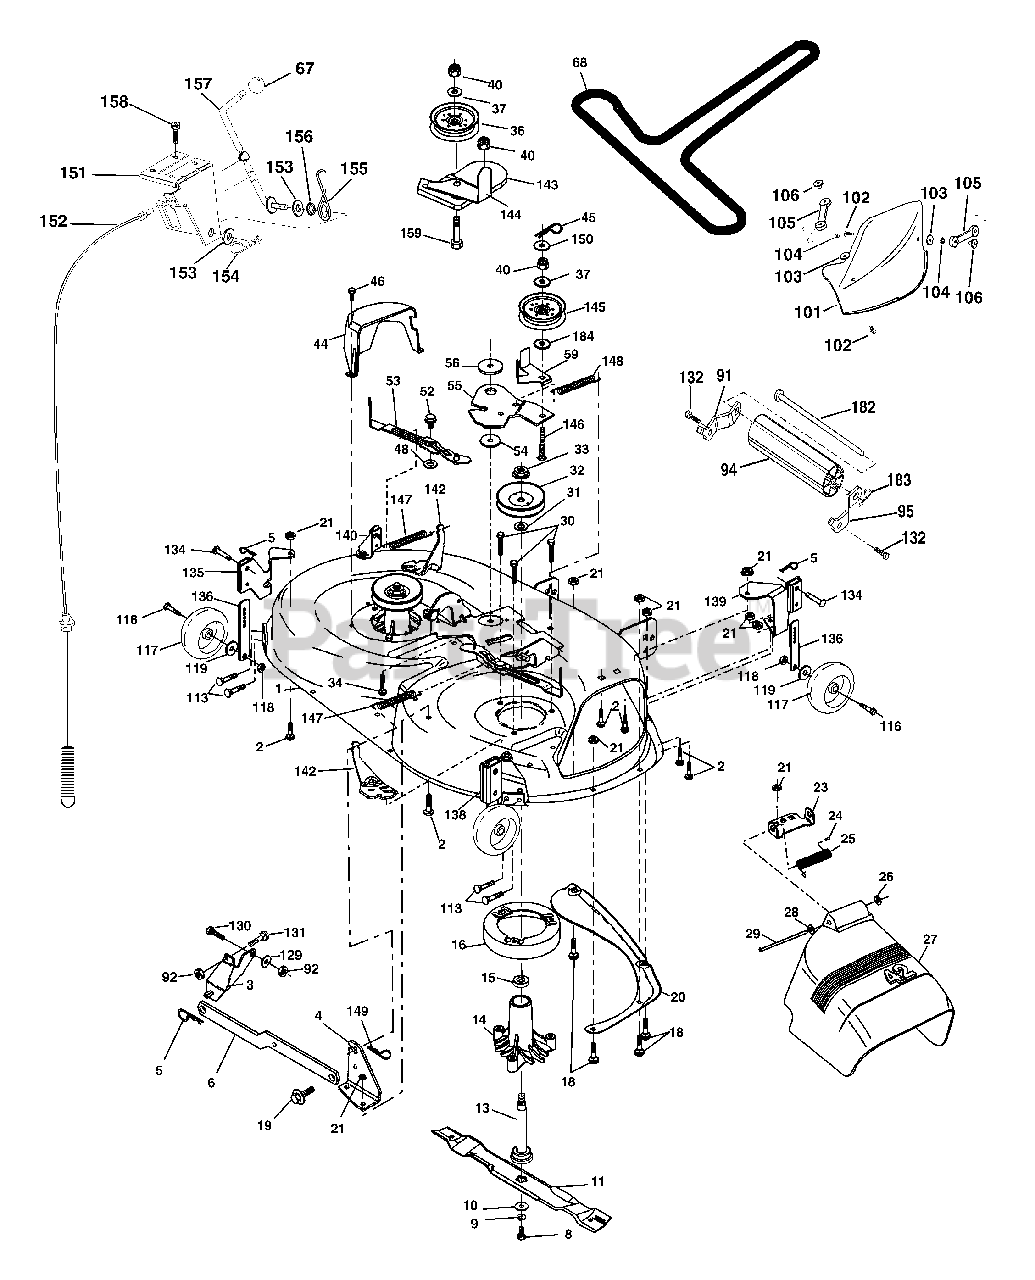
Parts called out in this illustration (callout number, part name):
1	Mower Deck Assembly, 42"
2	Bolt
3	Bracket Asm Fr. Sway Bar 3/42
4	Bracket Asm Deck 42" Sway Bar
5	Retainer Spring
6	Bar Sway Deck
8	Bolt 3/8-24 x 25 Grade 8 patched
9	Washer, Lock
10	Washer, Hardened
11	Blade, Mulching 42" Std
11	Blade Mulching 42" Premium
11	Blade Mower 42" Hi-Lift
13	Shaft Assembly, Mandrel, Vented
14	Housing, Mandrel, Vented
15	Bearing, Ball, Mandrel
16	Stripper, Mandrel Deck
18	Bolt, Carriage 5/16-18 x 5/8
19	Bolt, Shoulder
20	Baffle, Vortex
21	Nut
23	Bracket, Deflector Mower 42"
24	Cap, Sleeve 80 x 112 Blk Mower
25	Spring, Torsion, Deflector 2 52
26	Nut, Push Phos & Oil
27	Shield, Deflector 42" Blk
28	Washer 11/32 x 5/8 x 16 Gauge
29	Rod, Hinge 42" 6 75 W/G
30	Screw Thdrol
31	Washer, Spacer Mower Vented
32	Pulley, Mandrel
33	Nut, Toplock
34	Bolt
36	Pulley, Idler, Flat
37	Washer 13/32 x 13/16 x 16 Gauge
40	Nut
44	Guard, Mandrel, LH
45	Retainer
46	Screw, Thdrol 1/4-20 x 5/8 T
48	Washer, Hardened
52	Bolt, Shoulder 5/16-18 Unc
53	Arm Assembly, Pad, Brake
54	Washer, Hardened
55	Arm, Idler
56	Spacer, Retainer
59	Guard TUV Idler
67	Knob Round
68	V-Belt, 42" Mower
91	Bracket Asm Noseroller LH
92	Nut Lock Hex w/Ins 3/8-16 Unc
94	Roller Nose 38 & 42
95	Bracket Asm Noseroller RH
101	Mulcher Cover
102	Screw, Pan Hd Phillip 10-24 x 5/8
103	Washer, Flat
104	Washer, Lock
105	Latch Assembly
106	Nut, Weld
113	Screw 5/16-18 x 3/4
116	Bolt, Shoulder
117	Wheel, Gauge
118	Nut Centerlock 3/8-16
119	Washer 3/8 x 7/8 x 14 Ga.
129	Washer 13/32 x 13-16 x 12 Ga
130	Bolt Fin Hex 3/8-16 x 1 Gr. 5
131	Bolt RDHD SQNK 3/8-16 x 1
132	Screw 3/8-16 x .75
134	Pin Head Rivet
135	Bracket Asm. Whl Ga. R LH
136	Bar Adjusting Gauge Wheel
138	Bracket Asm Whl Ga. R RH
139	Bracket Asm. Whl Ga. F RH
140	Bracket Asm Whl Ga. F LH
142	Arm Spring Brake Mower
143	Bracket Arm Idler 42"
144	Keeper Belt 42" Clutch Cable
145	Pulley Idler Flat
146	Bolt Carriage Idler
147	Spring Extension
148	Spring Return Idler
149	Retainer Spring Yellow
150	Washer 9/32 x 3/4 x 16 Ga.
151	Bracket Clutch Cable
152	Clutch Cable 42"
153	Washer Flat 3/8" Type B
154	Spring Retainer
155	Spring Retention LVR CLTCH CAB
156	Spacer Clutch Cable
157	Rod Clutch Cable 3/8"
158	Screw Hex Thd Cut 1/4-20 x 1/2
159	Bolt Rdhd Sqn 3/8-16 Unc x 1-3/4
182	Rod Roller Nose
183	Retainer Spring
184	Washer 13/32 x 7/8 x 10 Ga.
